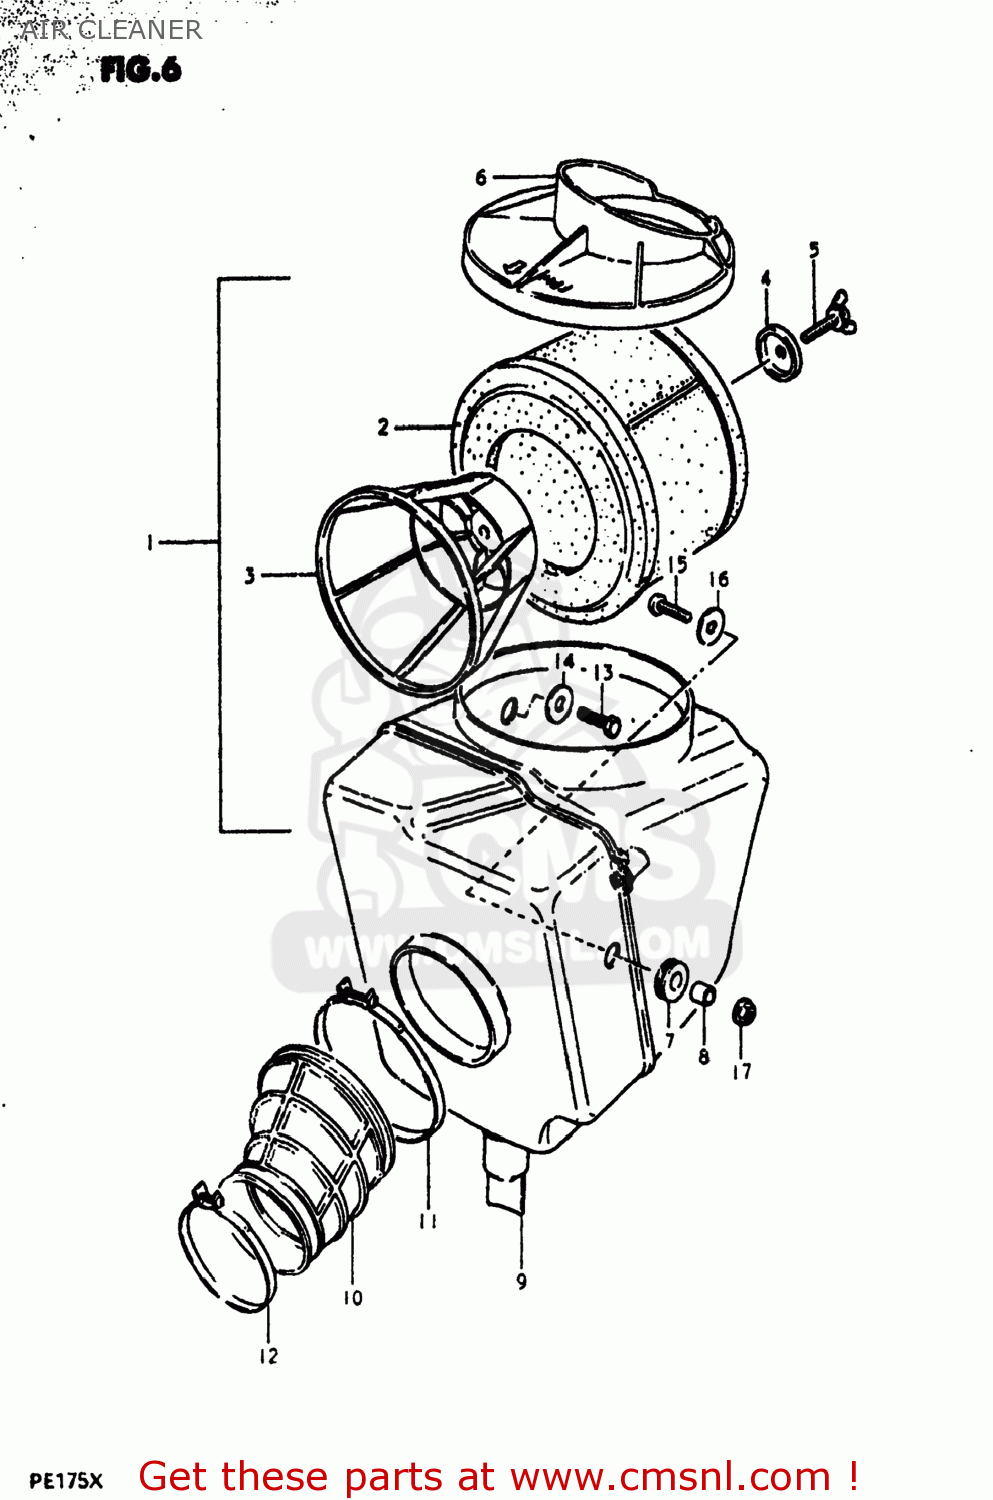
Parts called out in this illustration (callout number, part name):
1	CLEANER ASSEMBLY,AIR
2	FILTER
3	HOLDER
4	HOLDER,FILTER
5	WING BOLT,AIR CLEANER
6	CAP,AIR CLEANER
7	CUSHION
8	SPACER (6.1X9X9)
9	DRAIN TUBE,AIR CLEANER
10	HOSE,OUTLET
11	CLAMP
12	CLAMP
13	BOLT
14	WASHER (6.5X20X1.2)
15	SCREW
16	WASHER
17	NUT
